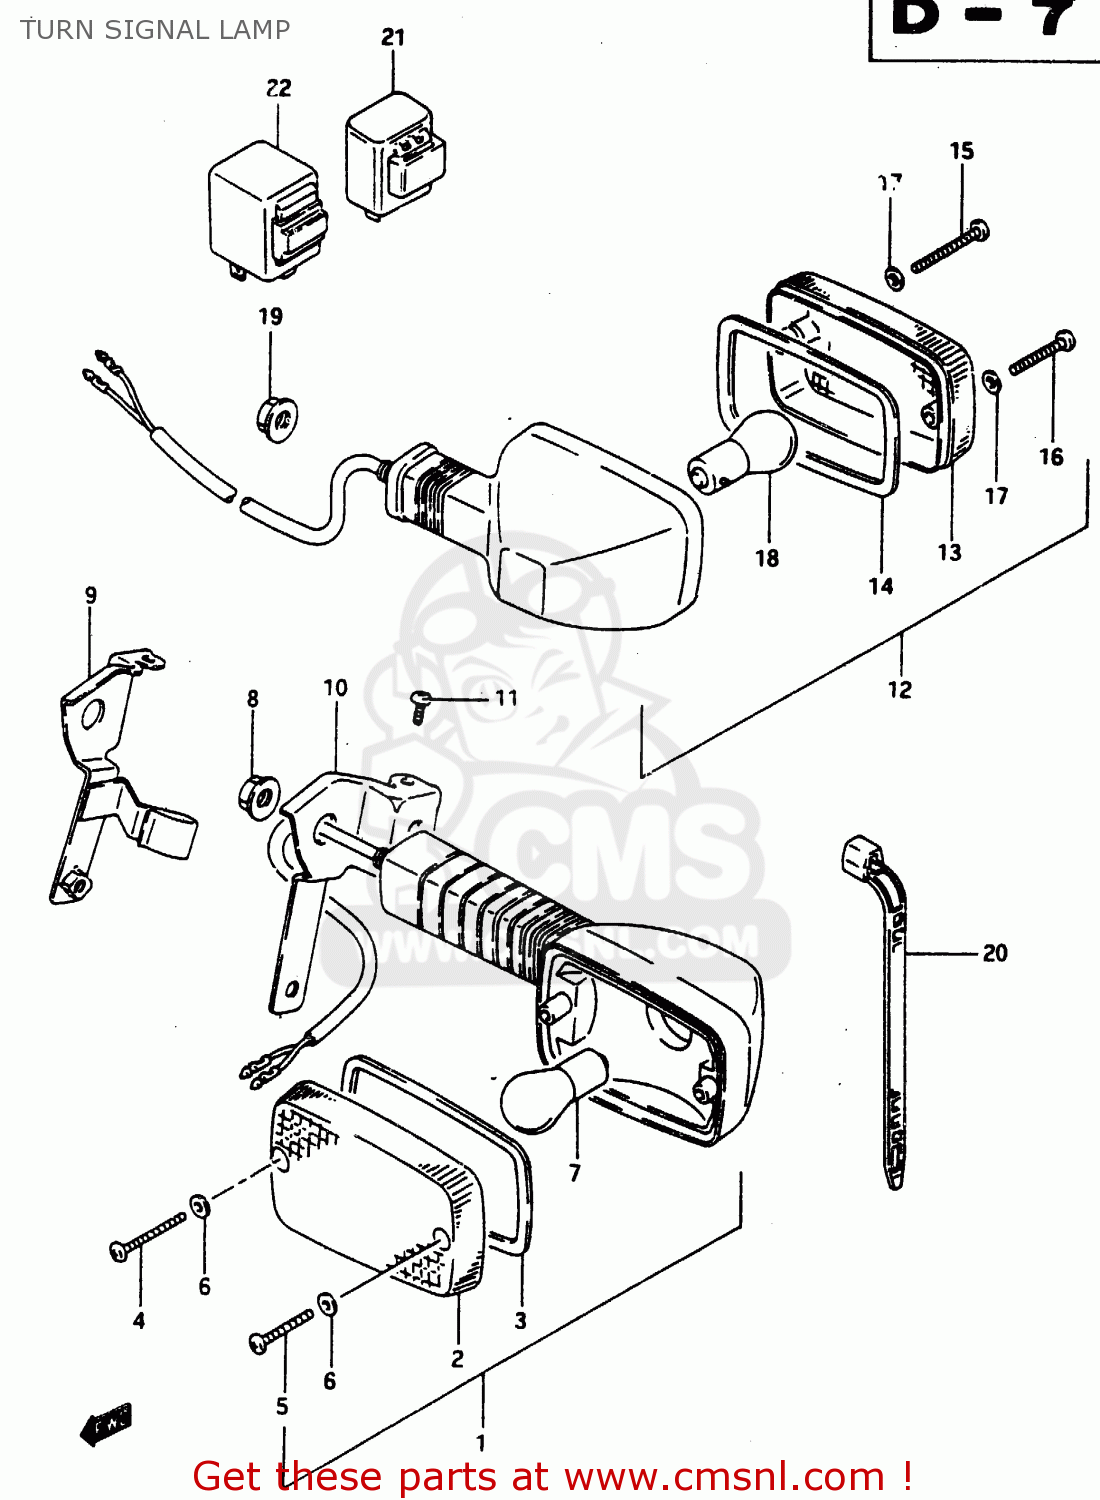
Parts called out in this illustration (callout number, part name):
1	LAMP ASSY,FR
2	LENS,FR
3	GASKET (NAS)
4	SCREW,TURN SIG LENS FITTING
5	SCREW
6	GASKET (NAS)
7	BULB(12V21W)
8	NUT
9	BRACKET,FRONT TURN SIGNAL
10	BRACKET,FRONT TURN SIGNAL
11	SCREW
12	LAMP ASSY,RR
13	LENS,RR
14	GASKET (NAS)
15	SCREW,TURN SIG LENS FITTING
16	SCREW
17	GASKET (NAS)
18	BULB(12V21W)
19	NUT
20	CLAMP(L:125)
21	RELAY ASSEMBLY,TURN SIGNAL
22	RELAY ASSY,TUR
